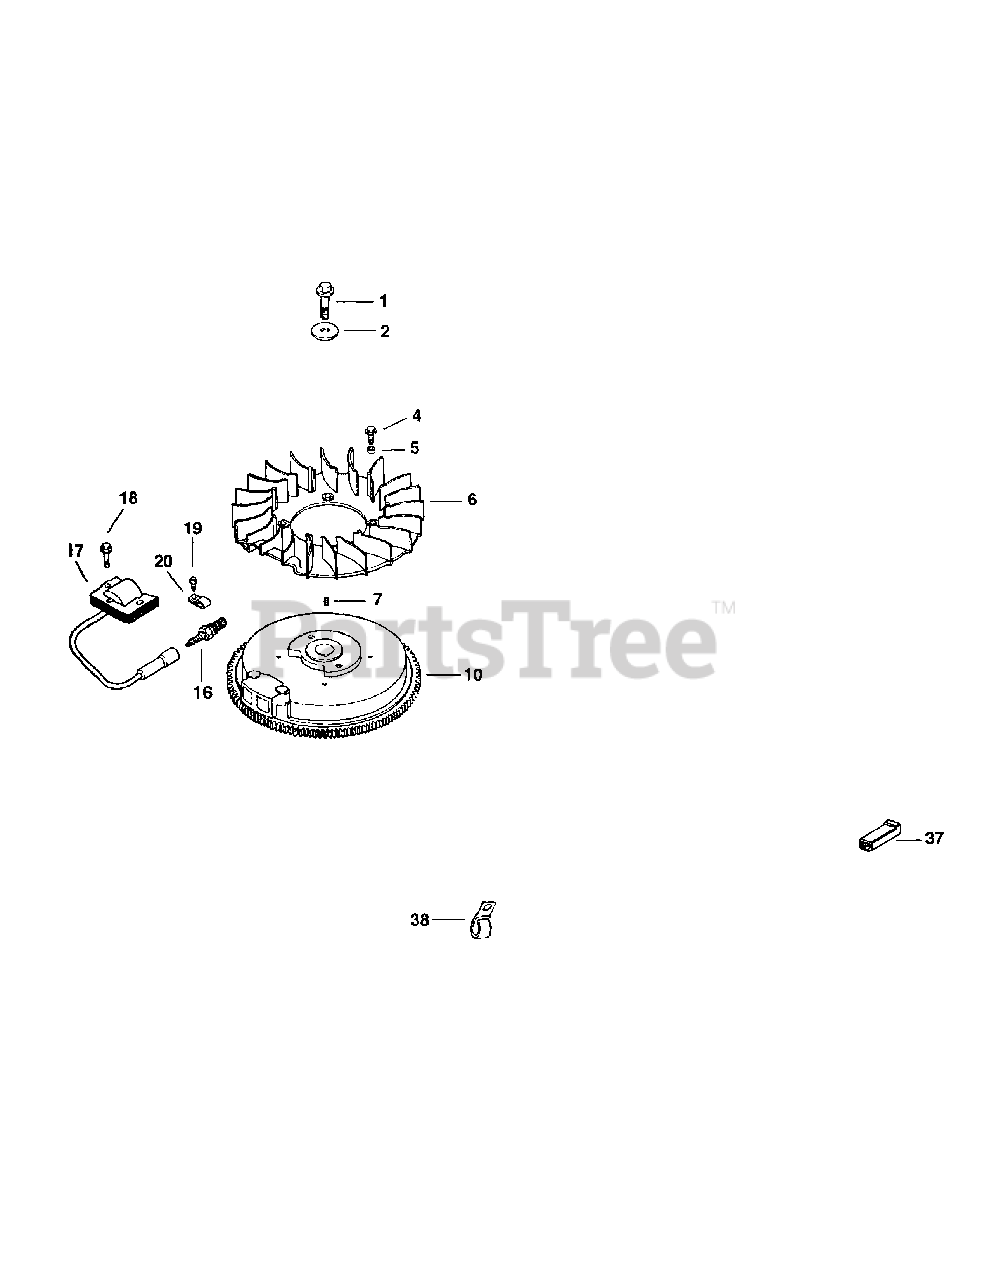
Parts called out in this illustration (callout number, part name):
1	Screw, Hex Flange
2	Washer, Plain 3/8"
4	Screw, Hex Flange
5	Spacer, Fan
6	Fan, Flywheel
10	Flywheel
13	Screw, Hex Flange
16	Spark Plug
17	Module, Ignition
18	Screw, Hex Flange
19	Screw, Hex Flange
20	Clip, Kill Lead
22	Cup And Screen
37	Connector
